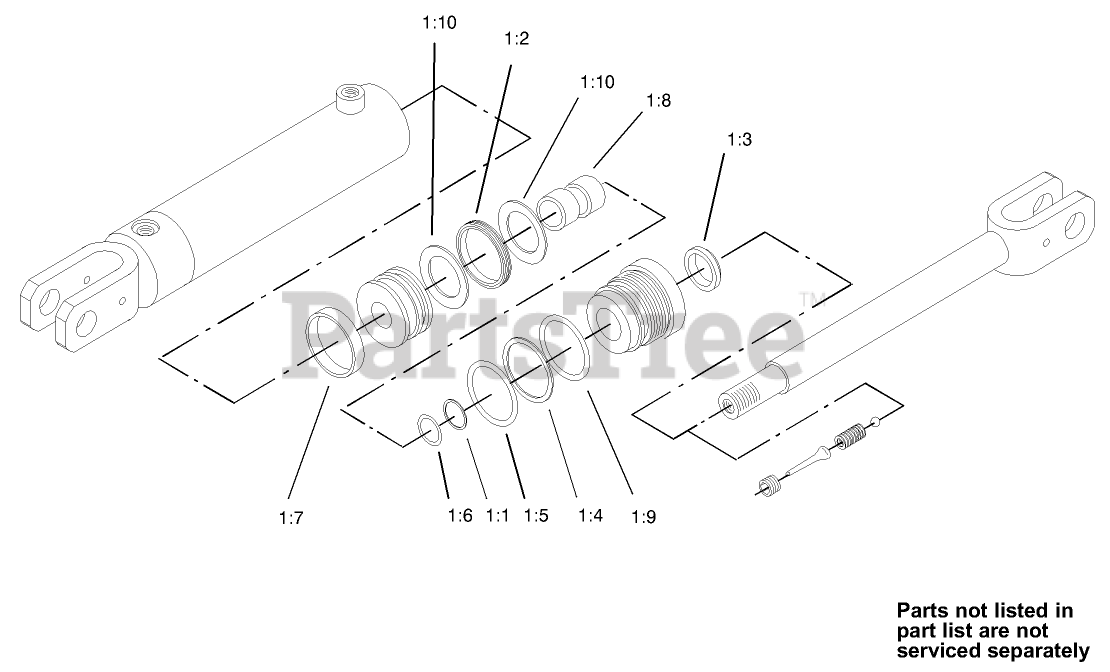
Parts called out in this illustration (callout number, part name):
1	SEAL KIT
1:1	Washer-Backup
1:2	PSP Seal
1:3	Rod-Wiper
1:4	Washer-Backup
1:5	Seal-Dust
1:6	Polypack
1:7	Ring-WEAR
1:8	Ring-WEAR
1:9	Seal-Dust
1:10	Washer-Backup
